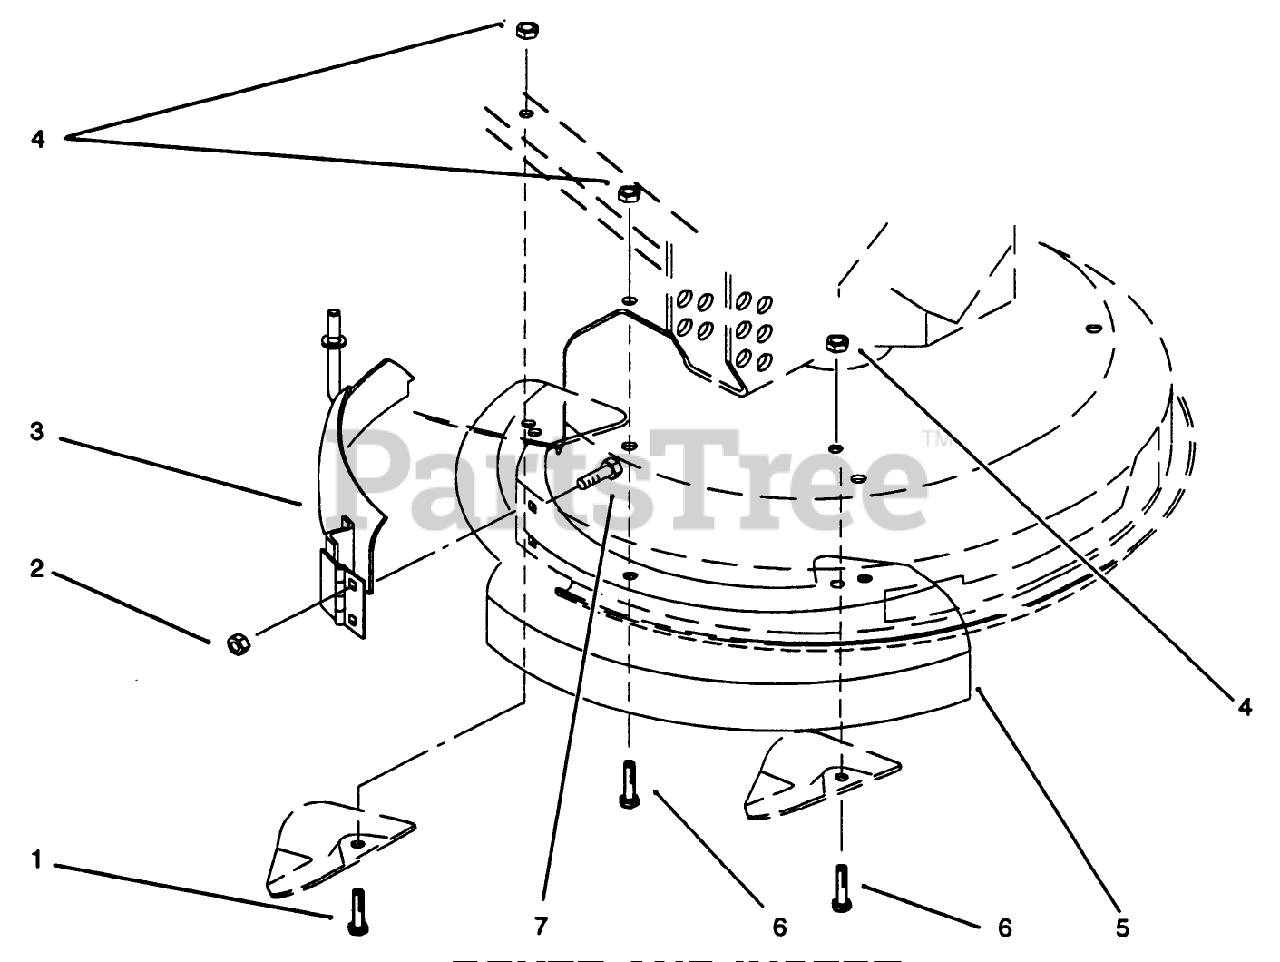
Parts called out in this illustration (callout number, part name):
1	SCREW-HH
2	NUT-KEPS
3	Cover-Front
4	NUT-LOCK, NI
5	Insert-Deck
6	Screw (Ref.)
7	SCREW-CARRIAGE
